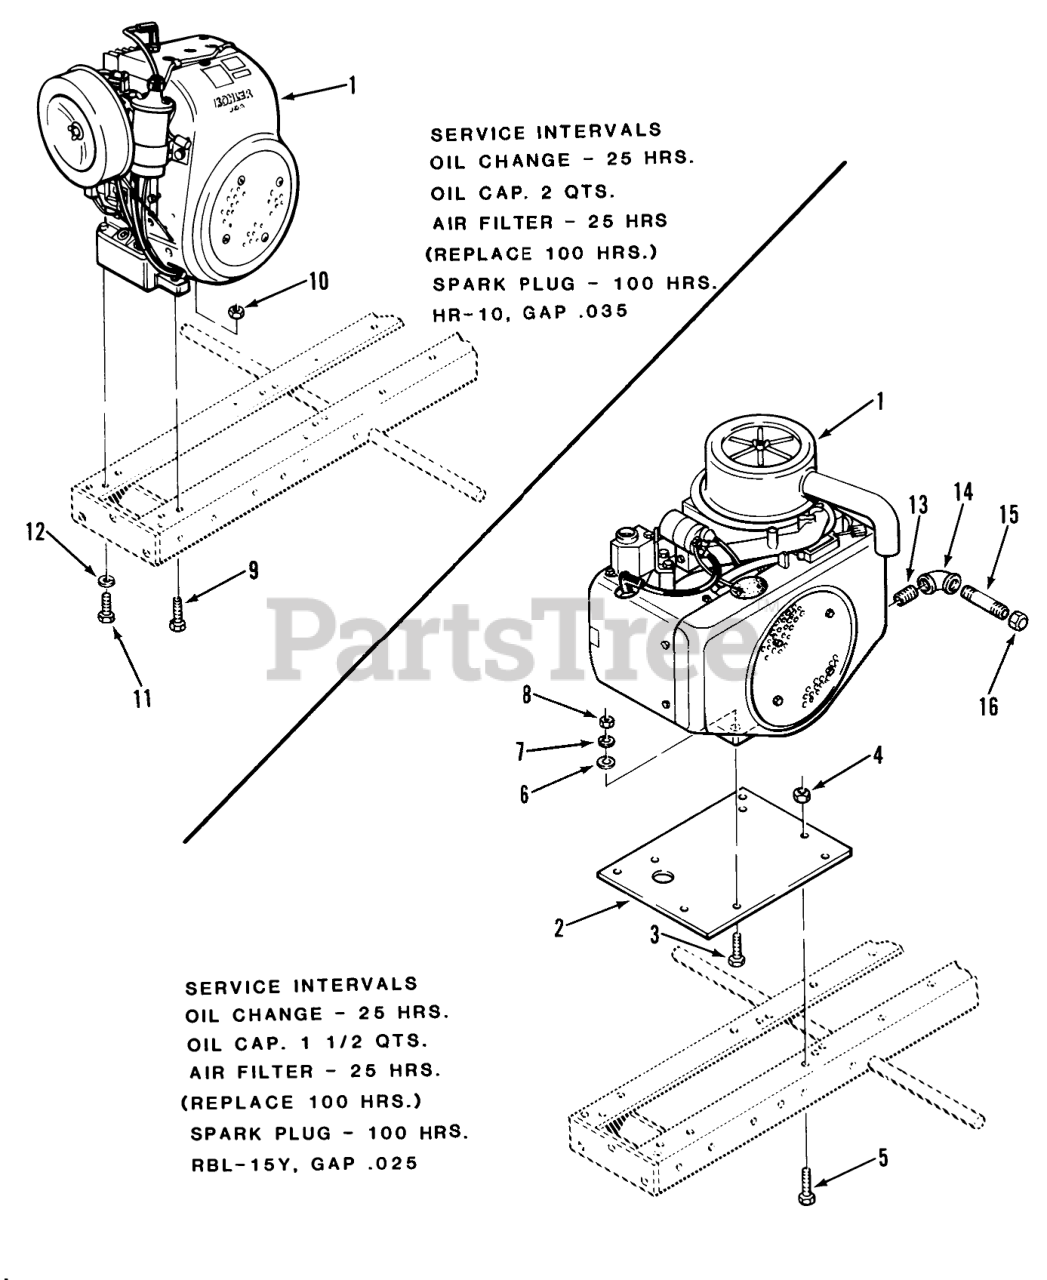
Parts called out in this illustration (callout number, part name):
1	Engine-14HP-Kohler K-321-S Spec PS-60424
1	Engine-17HP-Kohler KT-170S Spec PS-24350
1	Engine-10HP-Kohler K-241-S Spec PS-46849
1	Engine-12HP-Kohler K-301-S Spec PS-47812
1	Engine-16HP-Kohler K-341-S Spec PS-71371
1	Engine-17HP-Kohler KT-170S Spec PS-24340
